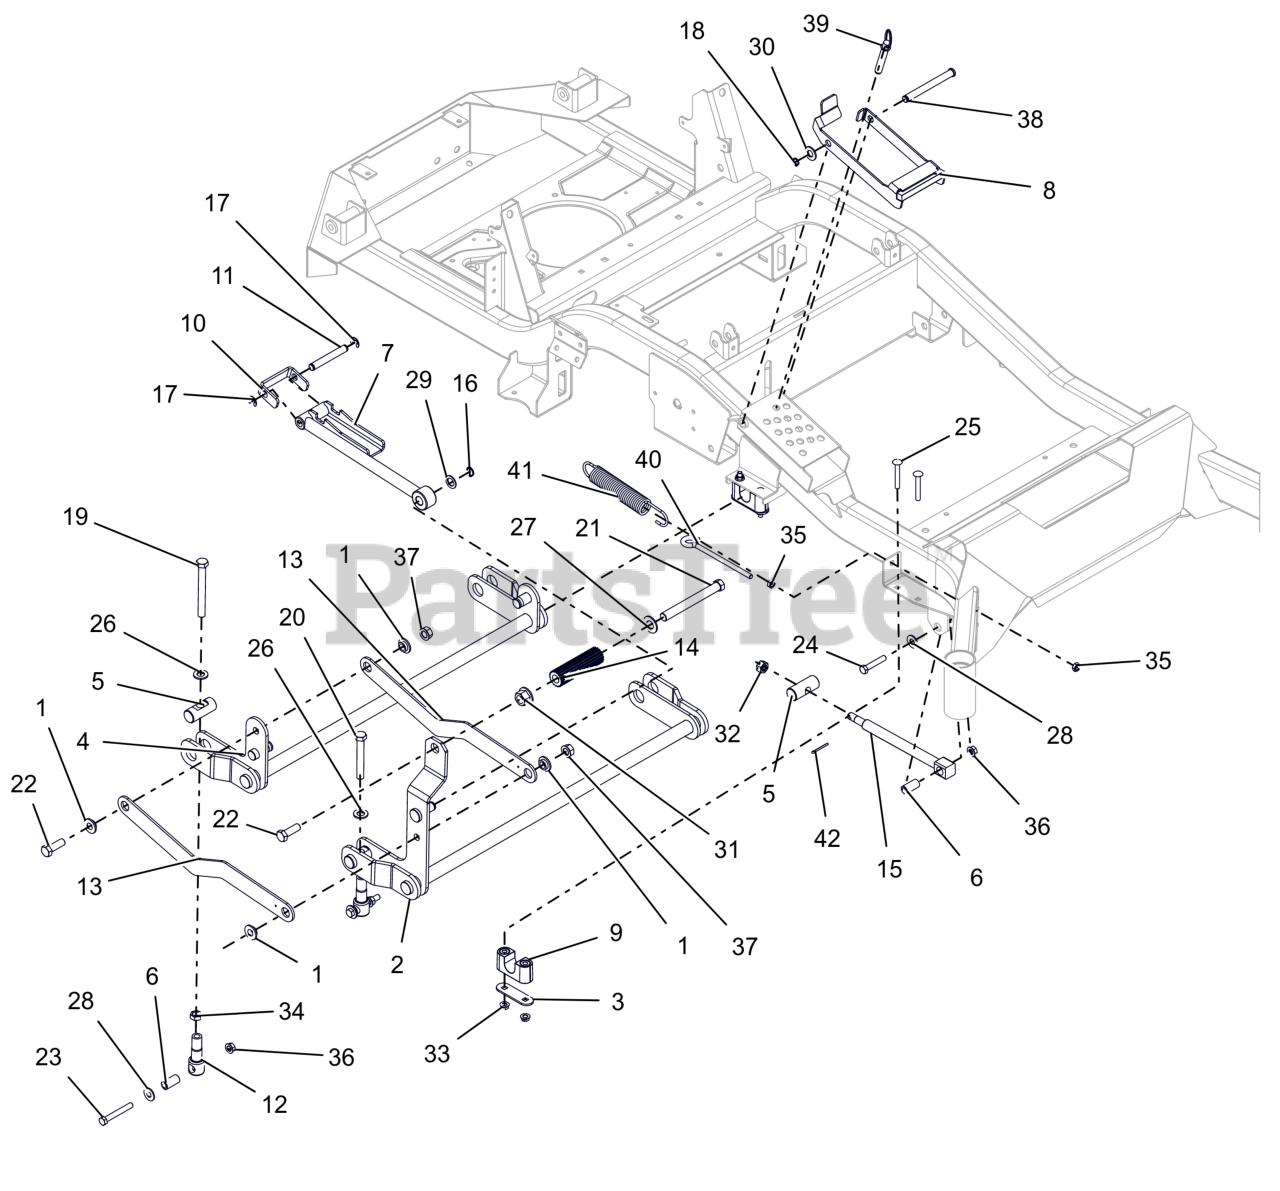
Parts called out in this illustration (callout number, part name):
1	BSHG-FLG .515X.750X.395X1.120
2	WLDMT, FRONT DECK LIFT PIVOT
3	PLATE, BEARING SUPPORT
4	WLDMT, REAR DECK LIFT PIVOT
5	PIN, DECK LIFT
6	SPACER, DECK LEVELING
7	WLDMT, HOC ARM
8	BRKT, HOC TRANSFER LOCK
9	ASM-BUSHING, DECK LIFT
10	BRKT, HOC LINE
11	ROD, HOC PIVOT
12	LINK, DECK LIFT FORMED
13	LINK, DECK LIFT
14	ROD, FOOT PEDAL (BLACK)
15	DRAG,LINK-HD
16	RG-RTNG-EXT .625X.050
17	RG-RTNG-EXT .500X.042 (E)
18	RG-RTNG-EXT .500X.050 (SNAP)
19	@BLT-HEX .5-13-4.5GR8 FULL THD
20	BLT-HEX .50-13X3.50 GR5 FTH
21	BLT, HEX .62-11X5.50 G5 FBP
22	@BLT-HEX .50-13X1.50 GR5 YWZC
23	BLT-HEX .38-16X2.75 GR8 YWZC
24	@BLT-HEX .38-16X2.00 GR5 YWZC
25	BLT-RDHDSQSHNK .31-18X2.25 YWZ
26	FLATWASHER 1/2 SAE HARD 15906
27	WSHRFLT 5/8SAE CARBHARD FBP
28	@WSHR-FL-STL.438X1.00X.083 YWZ
29	WSHR-FL-STL .630X1.005X.062 YZ
30	@WSHR-FL-STL.531X1.06X.095YWZC
31	NUT,FLG-TOP LK .625-11 FBP
32	NUT-SL .50-13
33	@NUT-LK-CTR-FLG .31-18 YZ GR F
34	NUT-JAM .50-13 YWZC
35	NUT-HEX-JAM .375-16 YWZC
36	@NUT-LK-TOP-FLG .38-16 YWZC
37	@NUT-LK-TOP-FLG .50-13 YWZC
38	PIN-CLEV .50X4.75X4.55
39	PIN, .50 X 2.20 USABLE LG BALL
40	BOLT,.38-16 X 5.25-.62 DIA EYE
41	SG-TENS .162X1.25X8.25 WLD 25
42	@PIN-CTR .12X1.25 EXTPRSQCT YZ
